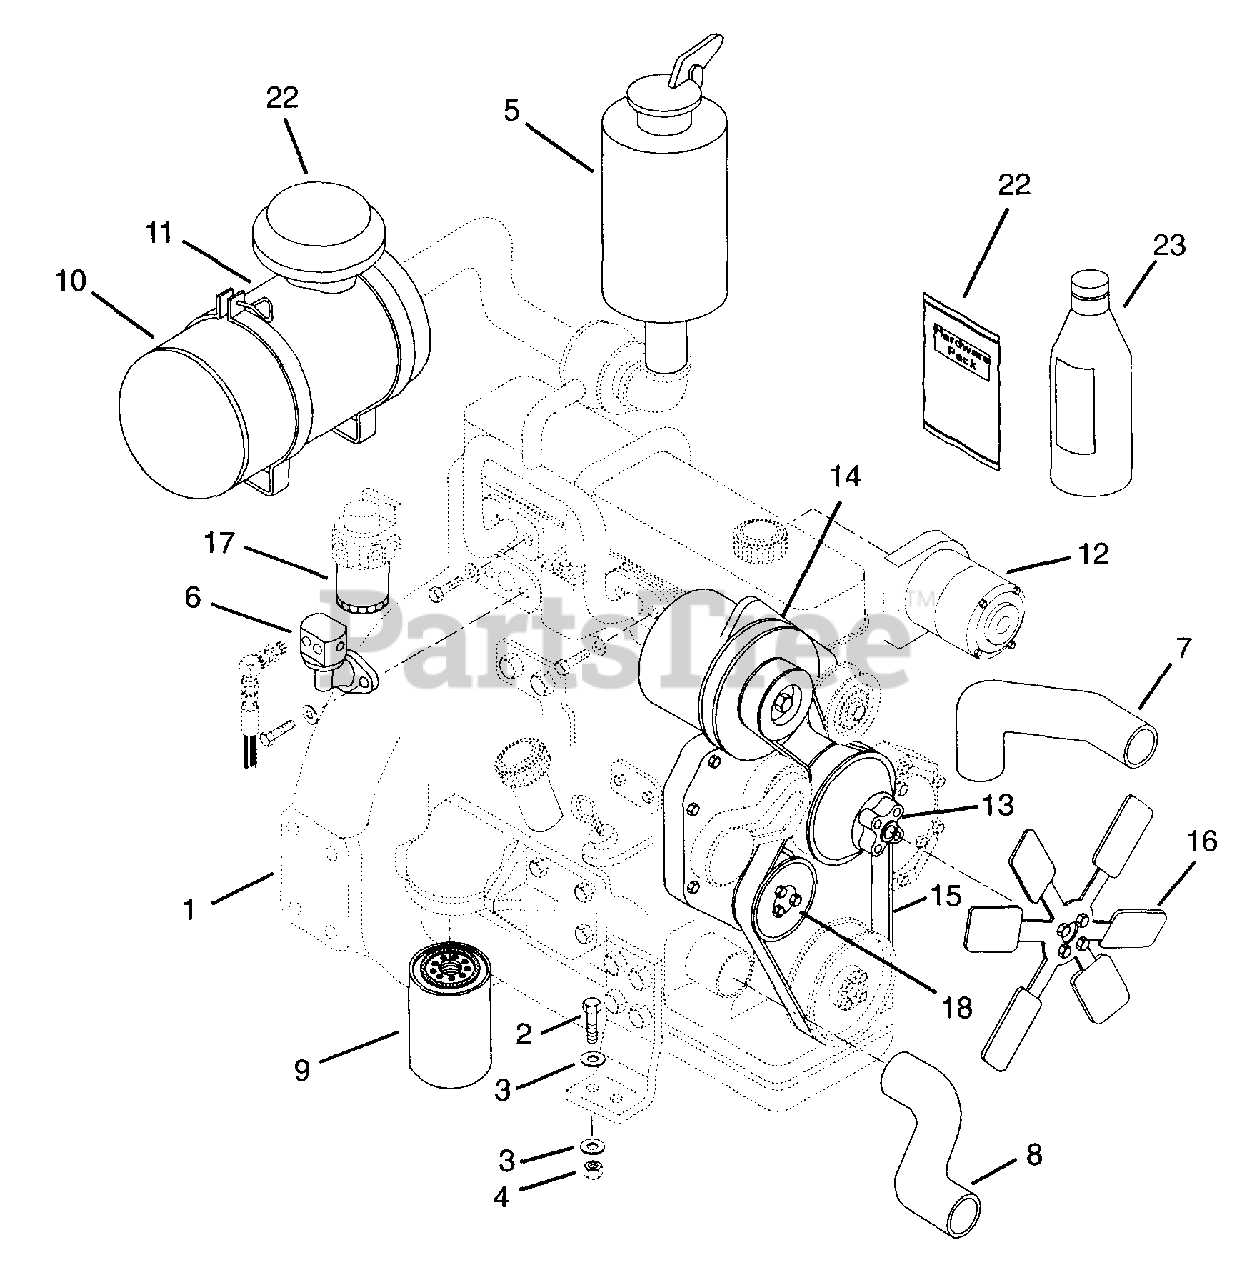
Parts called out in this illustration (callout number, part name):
1	Engine-John Deere 115 HP
2	Bolt-Hex .75-10 x 2.50 Grade 5
3	Washer-Flat-Steel .813 x 2.000 x .148
4	Nut-Locking-Center .75-10
6	Pump-Lift (Fuel)
7	Hose-Radiator-Top
8	Hose-Radiator-Bottom
9	Filter-Oil
10	Filter-Air-Primary
11	Filter-Air-Secondary
13	Pump-Water
13	Gasket, Water Pump
14	Alternator
17	Element-Fuel Filter
18	Pump-Oil
19	Kit-Gasket Overhaul
20	Gasket Set-(Tune-up) (Head Removal)
21	Cap-Air Intake
22	Test Kit-Coolant Conditioner
23	Conditioner-Coolant, 1/2 Gallon
